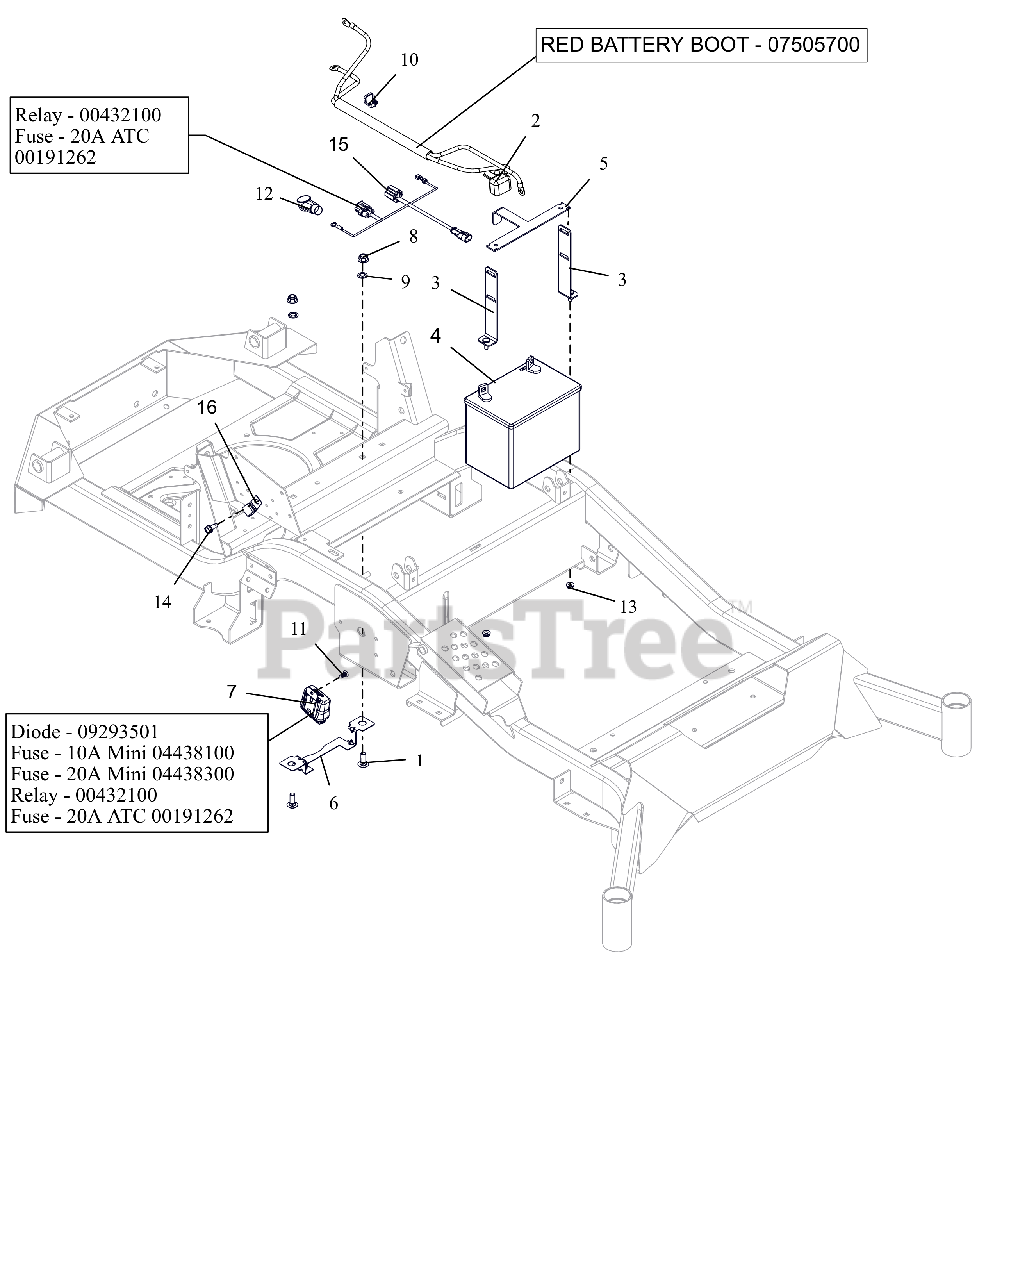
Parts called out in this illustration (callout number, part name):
1	BLT, RHSN .38-16X1.00 G5 ZCC
2	HARNESS, BATTERY HD
2	INSULATOR
3	WMT,BATTERY MOUNT HOLD DOWN
4	BATTERY, 300 CCA 10U1L
5	BRKT, BATTERY TIE DOWN
6	GUARD, ELECTRICAL HARNESS
7	HARNESS, WIRE
7	DIODE, CONNECTOR SHELL
7	FUSE,10 AMP MINI-ATC
7	FUSE,20 AMP MINI ATC
7	RELAY,SEALED W/DIODE
7	FUSE, 20 AMP BLADE S/O
8	NUT,NYL-FLG .38-16 GF ZCC
9	NUT-PUSH .38 DIA. PAL ZINC
10	CABLE TIE W/ TREE (.25 HOLE)
11	RIVET, .25 NYLON PANEL
12	BOOT, .65ID POS
13	NUT-LK-TOP-FLG .250-20 GF ZCC
14	SCR,TAP .312-18X.75 HWH TR ZCC
15	HARNESS, STARTER ADAPTOR
15	RELAY,SEALED W/DIODE
15	FUSE, 20 AMP BLADE S/O
16	J-CLAMP
